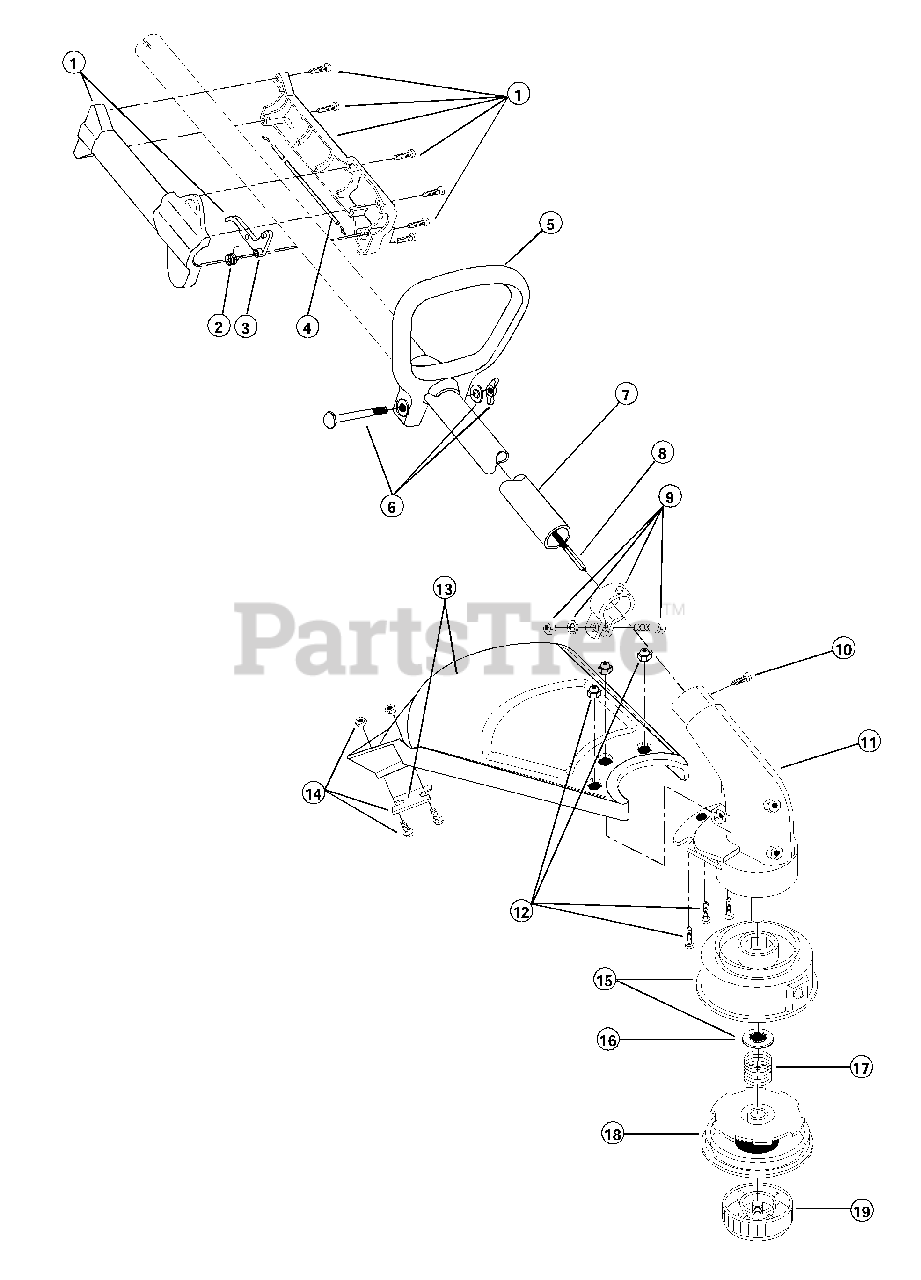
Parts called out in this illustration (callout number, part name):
1	Throttle Housing & Trigger Assembly
2	Throttle Trigger Spring
3	Throttle Trigger
4	Throttle Cable Assembly
5	D-Handle
6	D-Handle Hardware Assembly
7	Drive Shaft Housing Assembly
8	Flexible Drive Shaft
9	Lower Clamp Assembly
10	Anti-Rotation Screw
11	Gear Box Assembly
12	Shield Mounting Hardware
13	Shield and Blade Assembly
14	Blade Assembly
15	Outer Spool Assembly
16	Retainer
17	Spring
18	Inner Reel
19	Bump Head Knob Assembly
